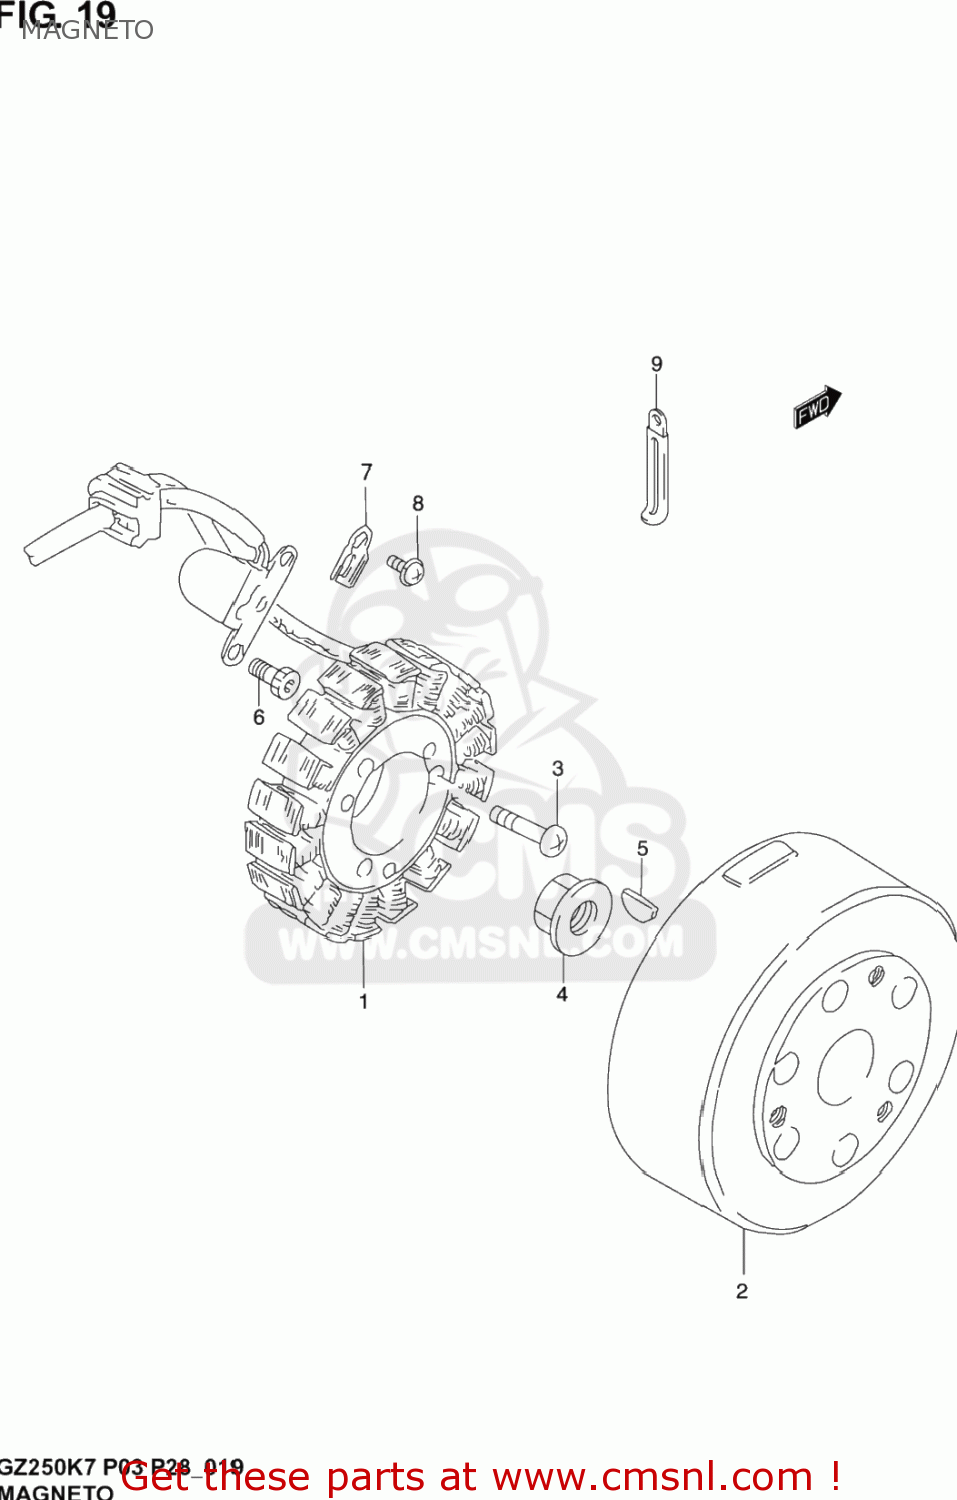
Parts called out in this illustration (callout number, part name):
1	STARTER ASSY
2	ROTOR ASSY
3	SCREW
4	NUT,GENERATOR ROTOR
5	KEY
6	BOLT
7	CLAMP,GENERATOR LEAD WIRE
8	SCREW
9	CLAMP(L:45)
